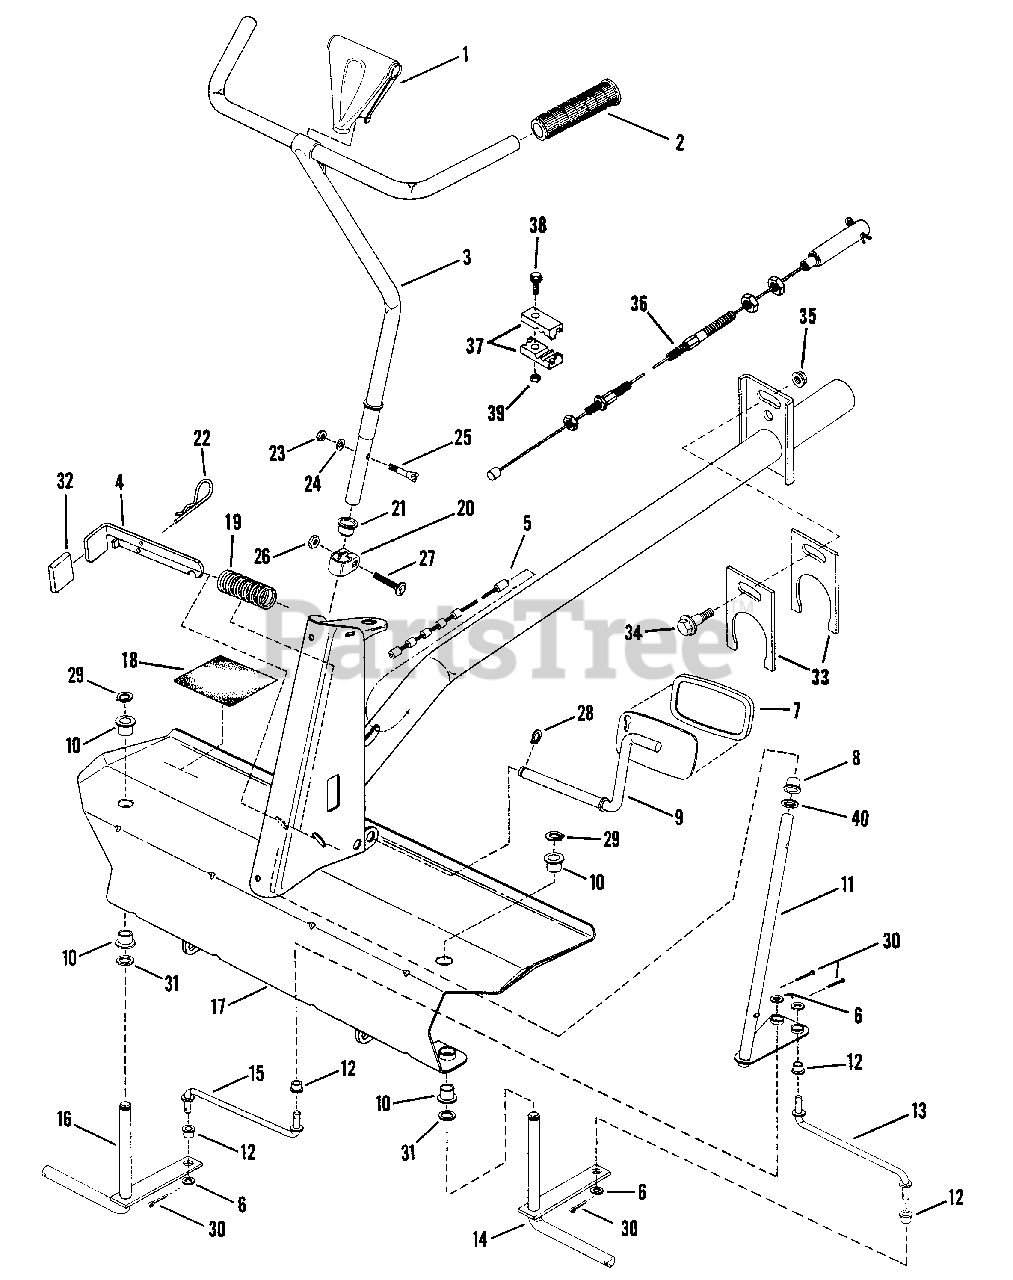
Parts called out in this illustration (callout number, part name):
1	COVER, Handle
2	GRIP, Handle
3	HANDLE, Steering (Black)
3	HANDLE, Steering (Red)
4	LATCH, Parking Brake
5	CABLE, Clutch/Brake
6	WASHER, 3/8" Flat
7	PAD, Clutch/Brake Pedal
8	BUSHING, Nylon
9	PEDAL, Clutch/Brake
10	BEARING
11	SHAFT, Steering
12	BUSHING, Tie-Rod
13	TIE-ROD, Left Hand
14	KING-PIN, Left Hand
15	TIE-ROD, Right Hand
16	KING-PIN, Right Hand
17	STRUCTURE, Front Axle
18	PAD, Foot
19	SPRING, Parking Brake
20	CLAMP, Steering
21	BUSHING, Nylon
22	PIN, Hair
23	NUT, 1/4-28 Hex
24	WASHER, 1/4 Internal Tooth Lock
25	BOLT, 1/4-28 Tapered Head
26	NUT, 5/16-18 Hex
27	BOLT, 5/16-18 x 1-1/2" Carriage
28	RING, Retaining
29	RING, Retaining
30	PIN, 1/8 x 3/4" Cotter
31	WASHER, 5/8 Flat
32	CAP, Parking Brake Lever
33	SPACER, Pivot
34	BOLT, 3/8-24 x 5/8" Hex Shoulder
35	NUT, 3/8-24 Hex Flange Lock
36	CABLE, Brake
37	CONNECTOR, Cable
38	BOLT, 1/4-20 x 3/4" Hex Cap
39	NUT, 1/4-20 Hex Center Lock
40	WASHER, 21/32 x 1-5/16" Dia.
